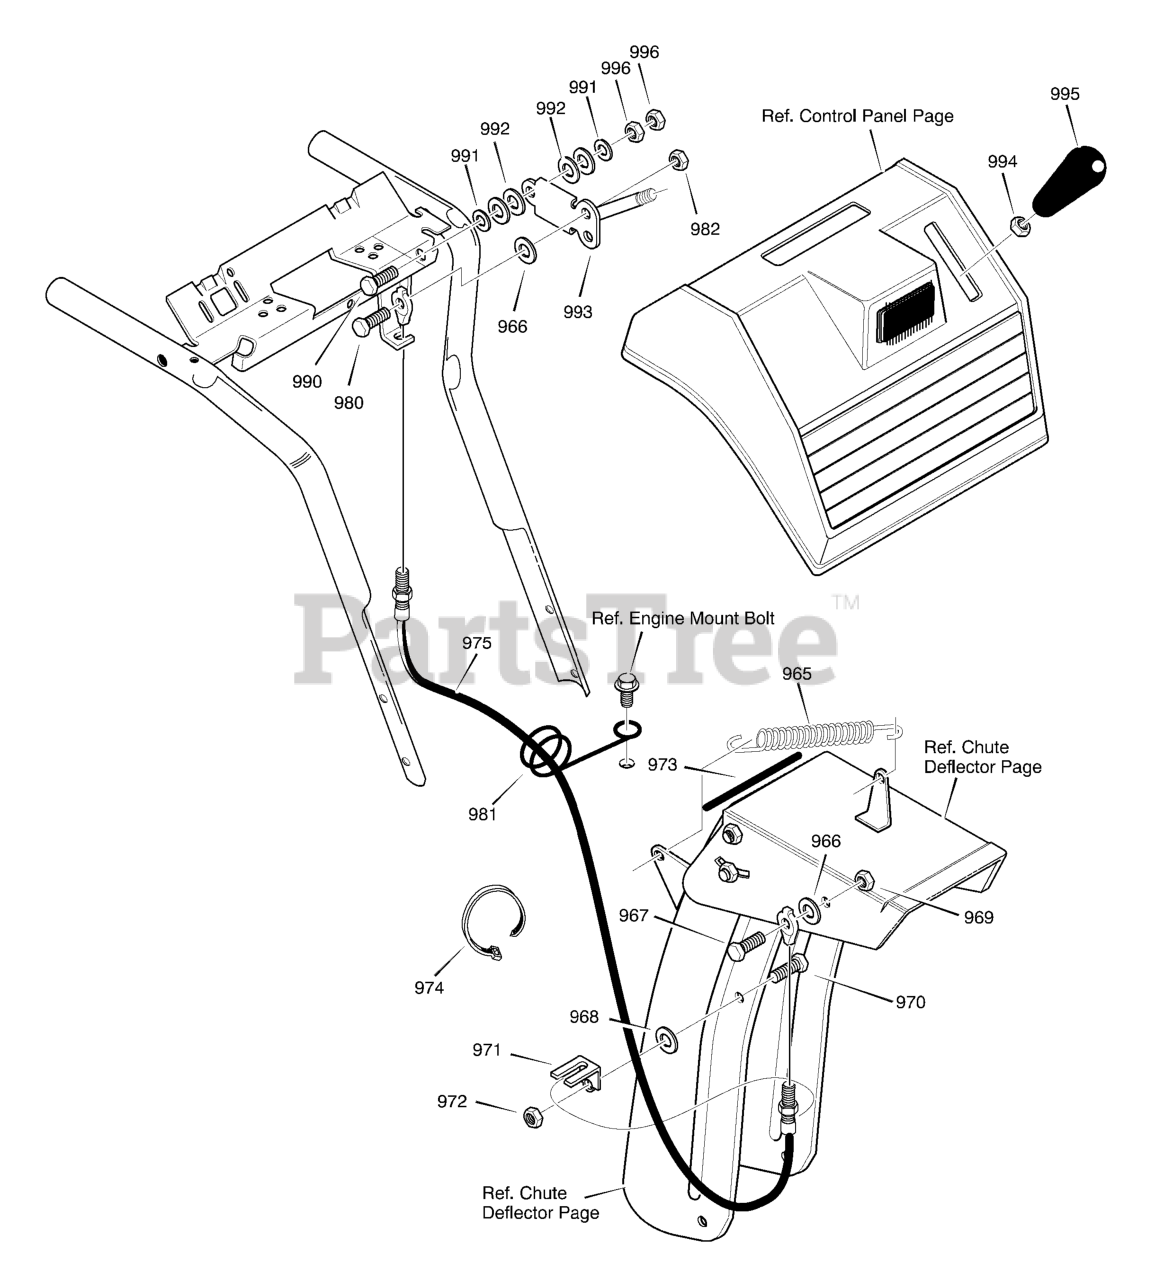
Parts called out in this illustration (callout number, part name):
965	SPRING, TENSION RETURN
966	WASHER, FLAT
967	BOLT, 5/16-18
968	WASHER, FLAT
969	NUT, 1/4-20
970	SCREW, 5/16-18 x 0.75
971	BRACKET, CABLE CHUTE
972	NUT, 5/16-18
974	TIE, CABLE
975	CABLE, CHUTE CONTROL
980	BOLT, 5/16-18
981	WIRE FORM
982	NUT, 1/4-10
990	SCREW, 3/8-16 x 1.75
991	WASHER, FLAT
992	WASHER, SPRING
993	HANDLE ASSY, SPEED CONTROL
994	NUT, 3/8-16 REGHEX
995	HANDLE, 3/8-16 MOLDED
996	NUT, 3/8-16 HEX
